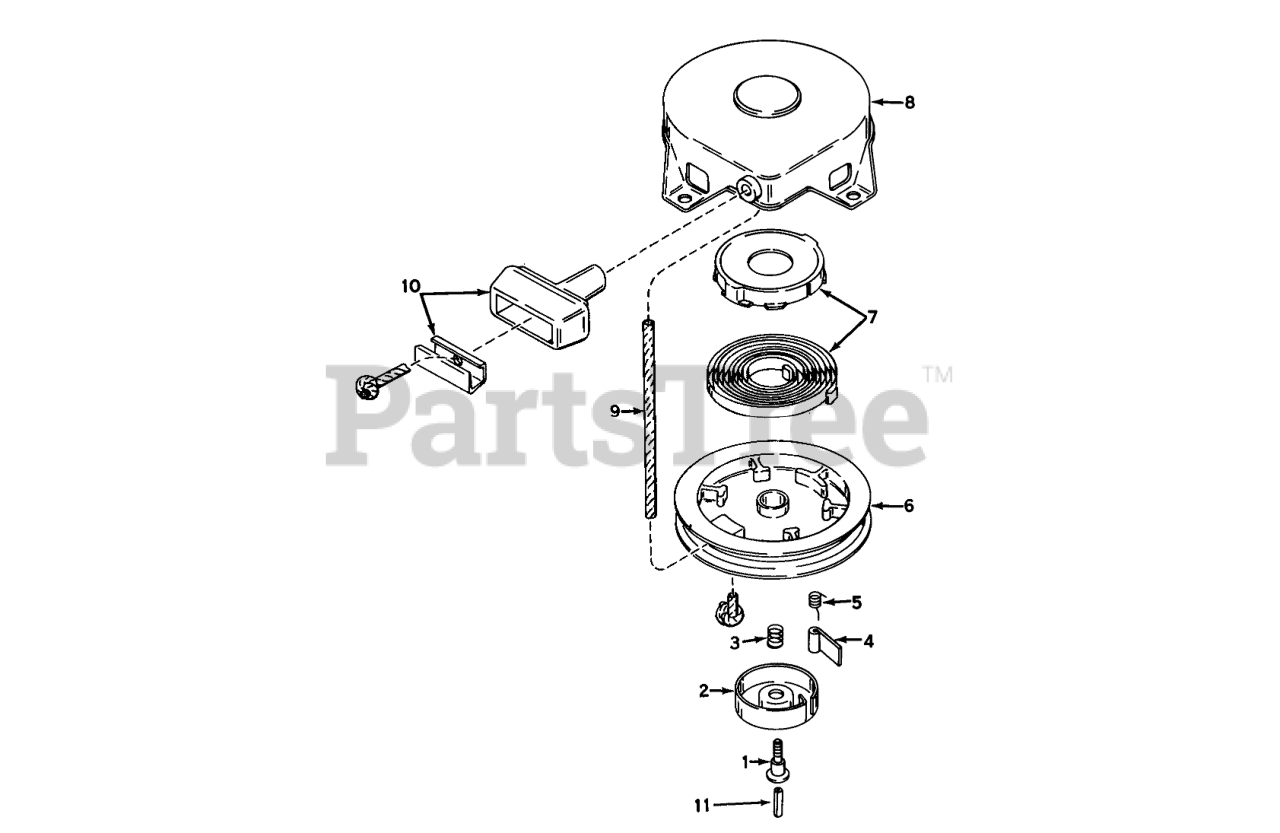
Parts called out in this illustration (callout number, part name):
2	Retainer
3	Spring-Brake
4	Dog-Starter
5	Spring-Dog
7	Spring & Keeper Assy
8	Housing Assy., Starter (Incl. Ref. #1)
9	Rope-Starter
10	Assy., Starter
11	Centering
